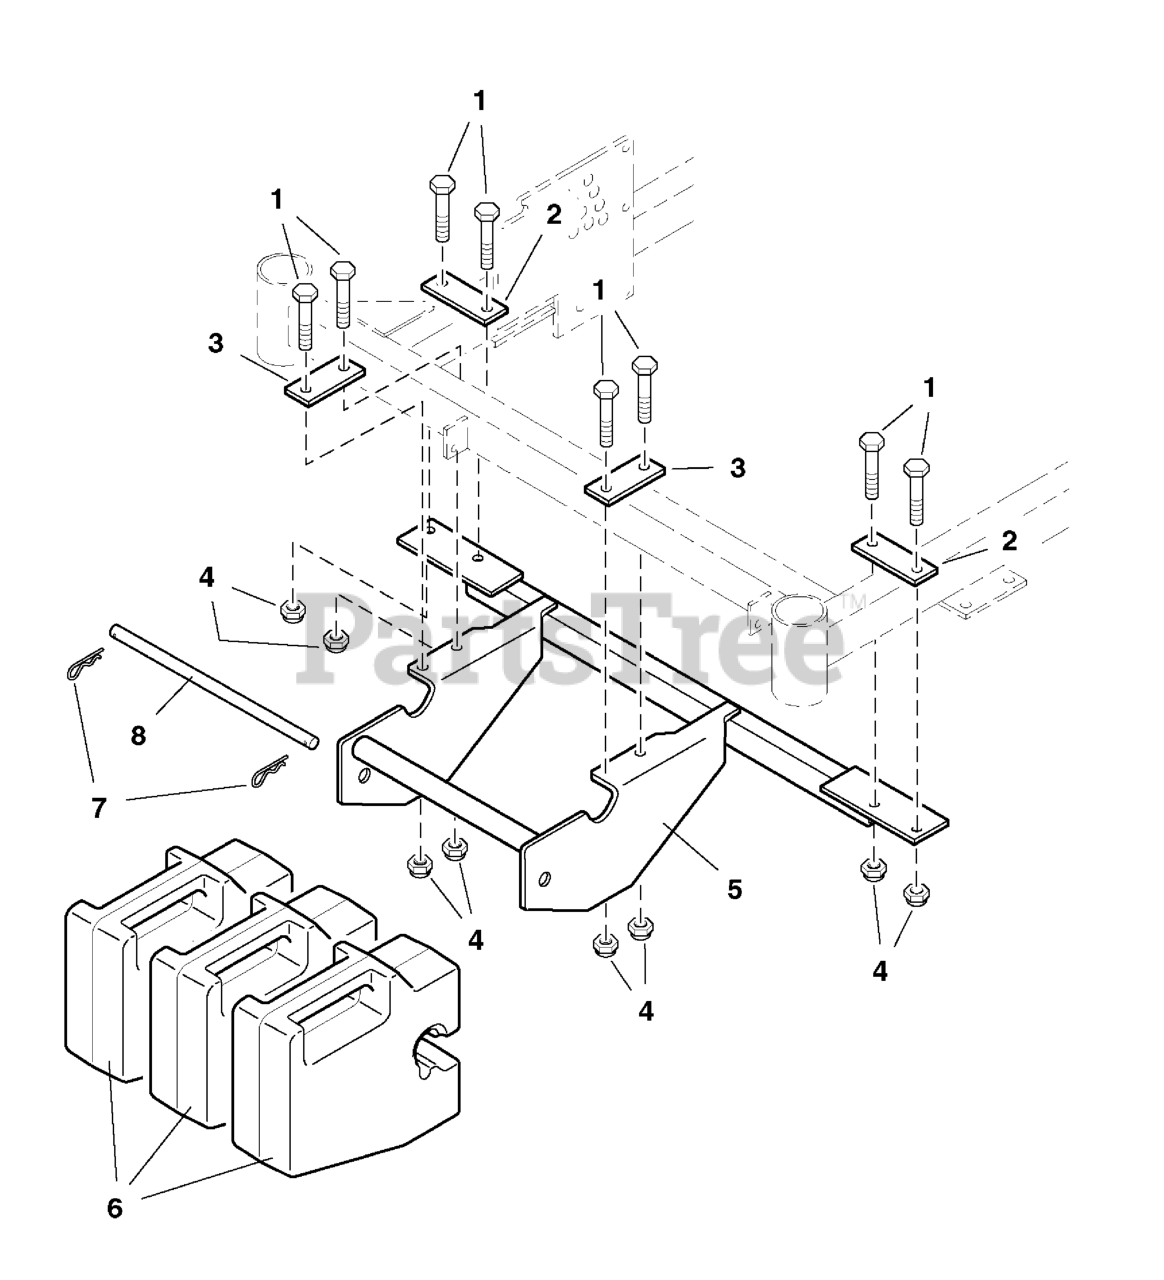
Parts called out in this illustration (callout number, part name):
1	BOLT, 3/8-16 X 3" GD5 CZ
2	BAR CLAMP - Side
3	BAR CLAMP - Front
4	NUT, 3/8-16 HEX NYLON LOCK
5	WEIGHT MOUNT
6	WEIGHT, 50 lbs.
7	HAIRPIN CLIP
8	RETAINER ROD
